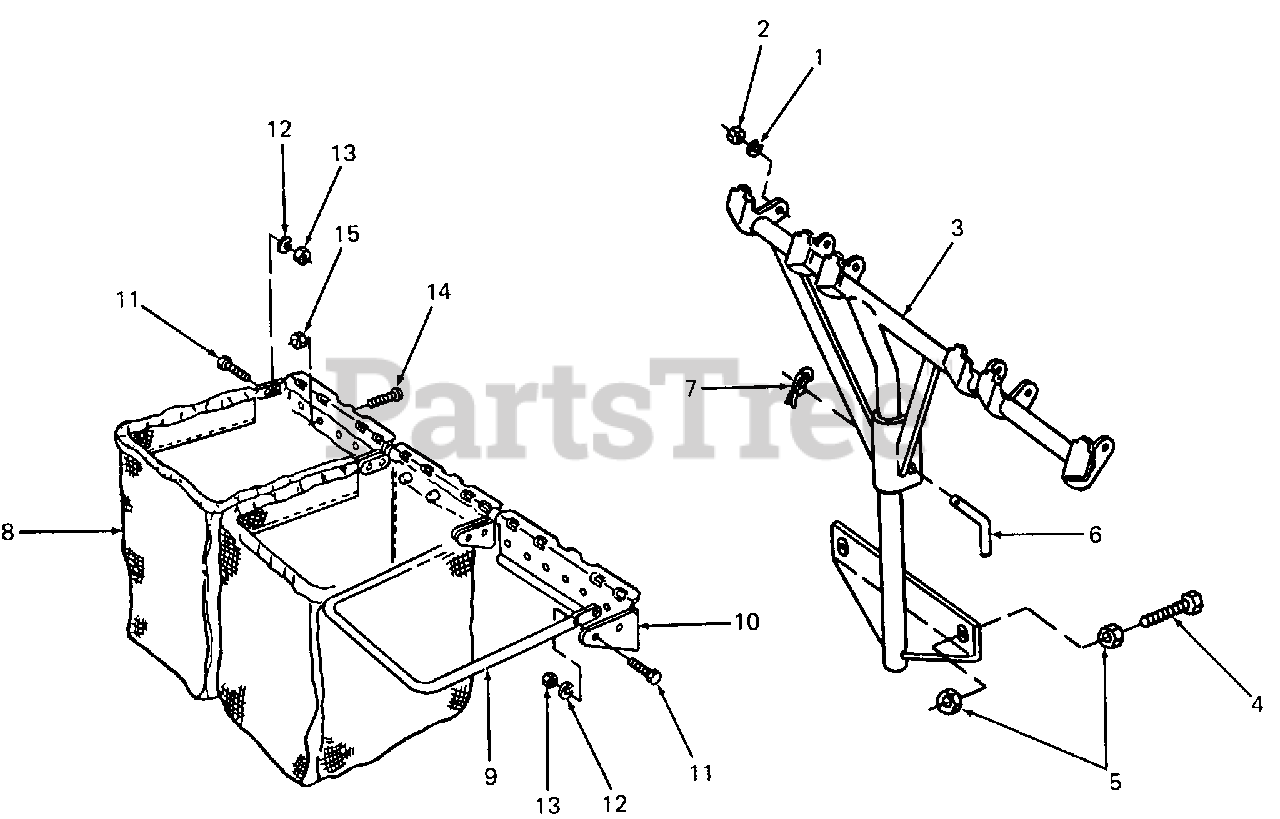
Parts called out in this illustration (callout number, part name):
1	Washer, Lock, 3/8
2	Nut, Hex, 3/8-16
5	Nut, Hex Jam, 3/8-16 GR5
6	Pin, Right Angle Clevis
7	Pin, Internal Cotter, 5/8 Dia
8	Bag, Grass Catcher
9	Frame, Catcher Bag
11	Screw, Hex Cap, 1/4-28 X .75 Lg
12	Washer, Lock, 1/4
13	Nut, Hex, 1/4-28
14	Screw, Truss Mach, #10-24 X .38 Lg
15	Nut, Hex Sems, #10-24
